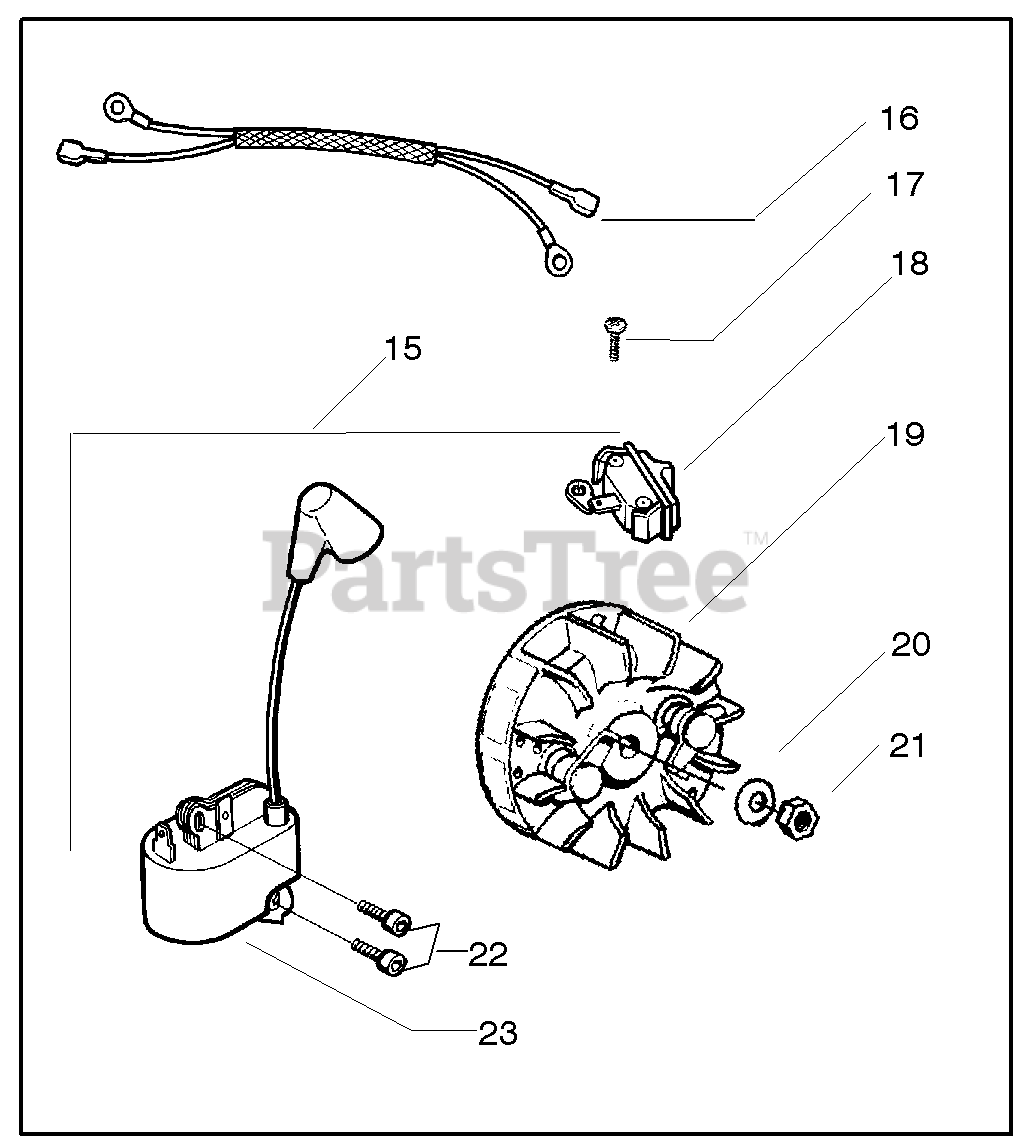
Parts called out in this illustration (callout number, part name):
15	Kit-EPS ignition
16	Assy-Leadwire
18	Switch-Ignition
19	Assy. -Flywheel
20	Washer-Flywheel
23	Module - Ignition
